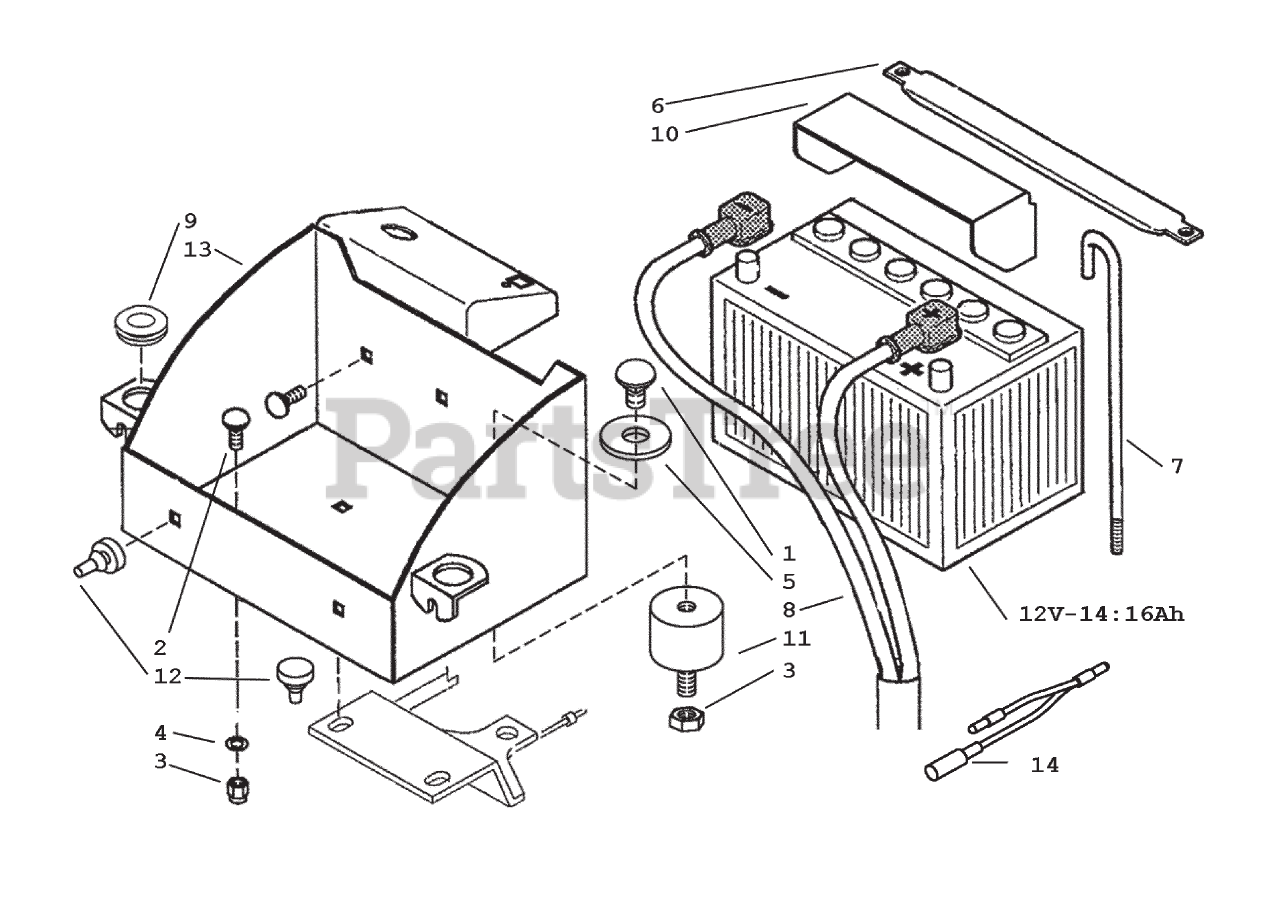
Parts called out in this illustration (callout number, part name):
1	BOLT W/SQUARE NUT, M6X12
2	BOLT, M6X16
3	LOCKNUT, STANDARD, M6
4	WASHER
5	WASHER, FLAT, M9X24
6	BATTERY BRACKET
7	ROD,BATTERY
8	CABLE, ELECTRIC START
9	SUPPORT, CAP
10	BATTERY COVER
11	SHOCK MOUNT
12	RUBBER CUSHIONS
13	BATTERY BOX
14	WIRING HARNESS (HONDA)
